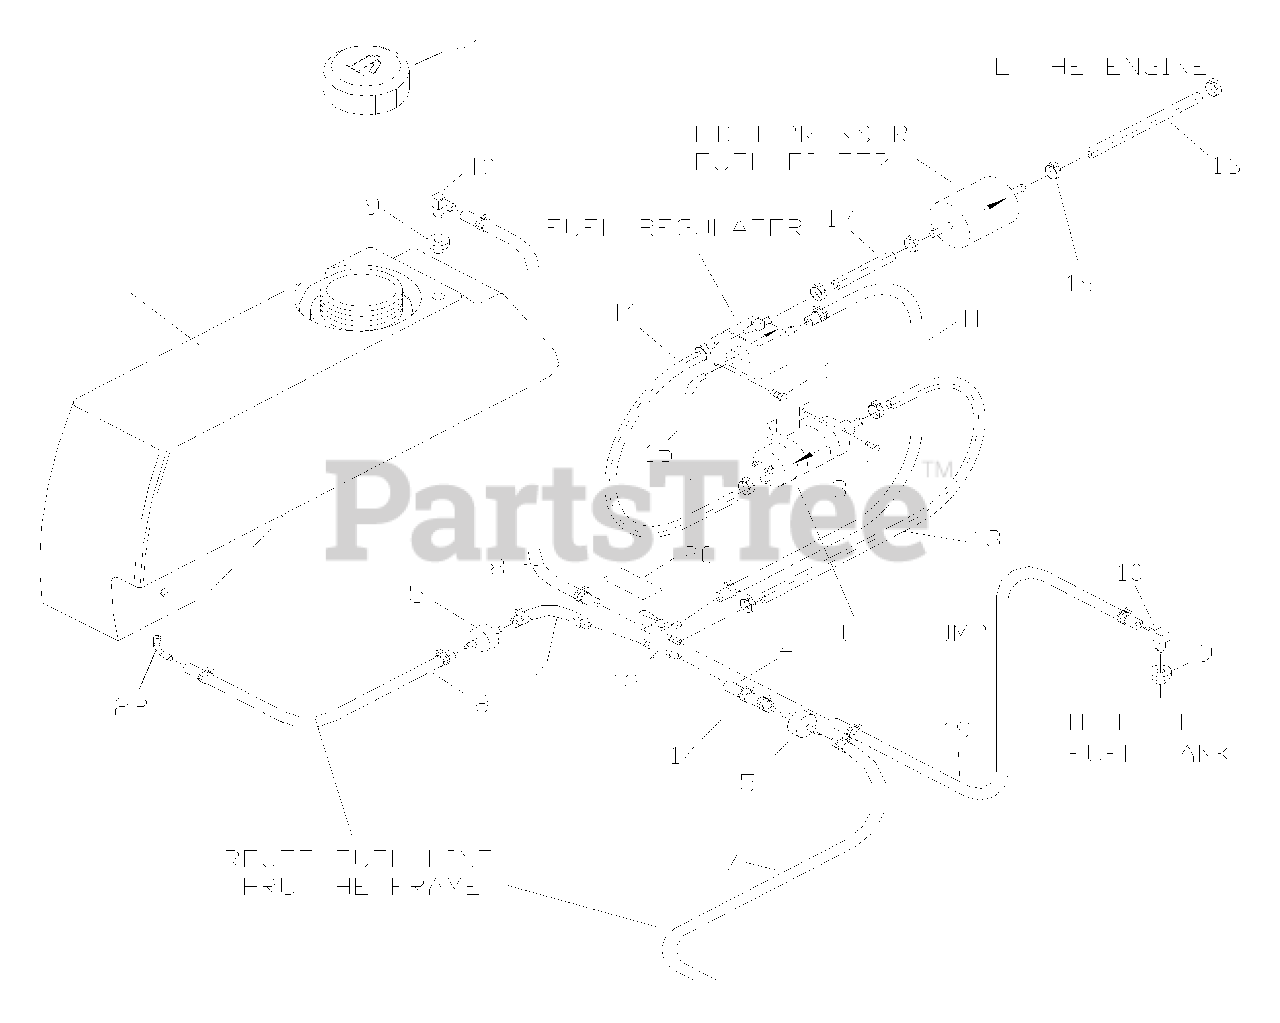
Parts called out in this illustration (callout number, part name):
1	FUEL TANK RT.
2	FUEL TANK LT.
3	SCREW SELF TAP
6	HCS 1/4 SELF TAP
7	FUEL LINE
8	FUEL LINE
9	RUBBER GROMMET
11	FUEL LINE
12	FUEL VALVE
14	HOSE CLAMP
21	FUEL CAP
22	TANK FITTING, 90°
